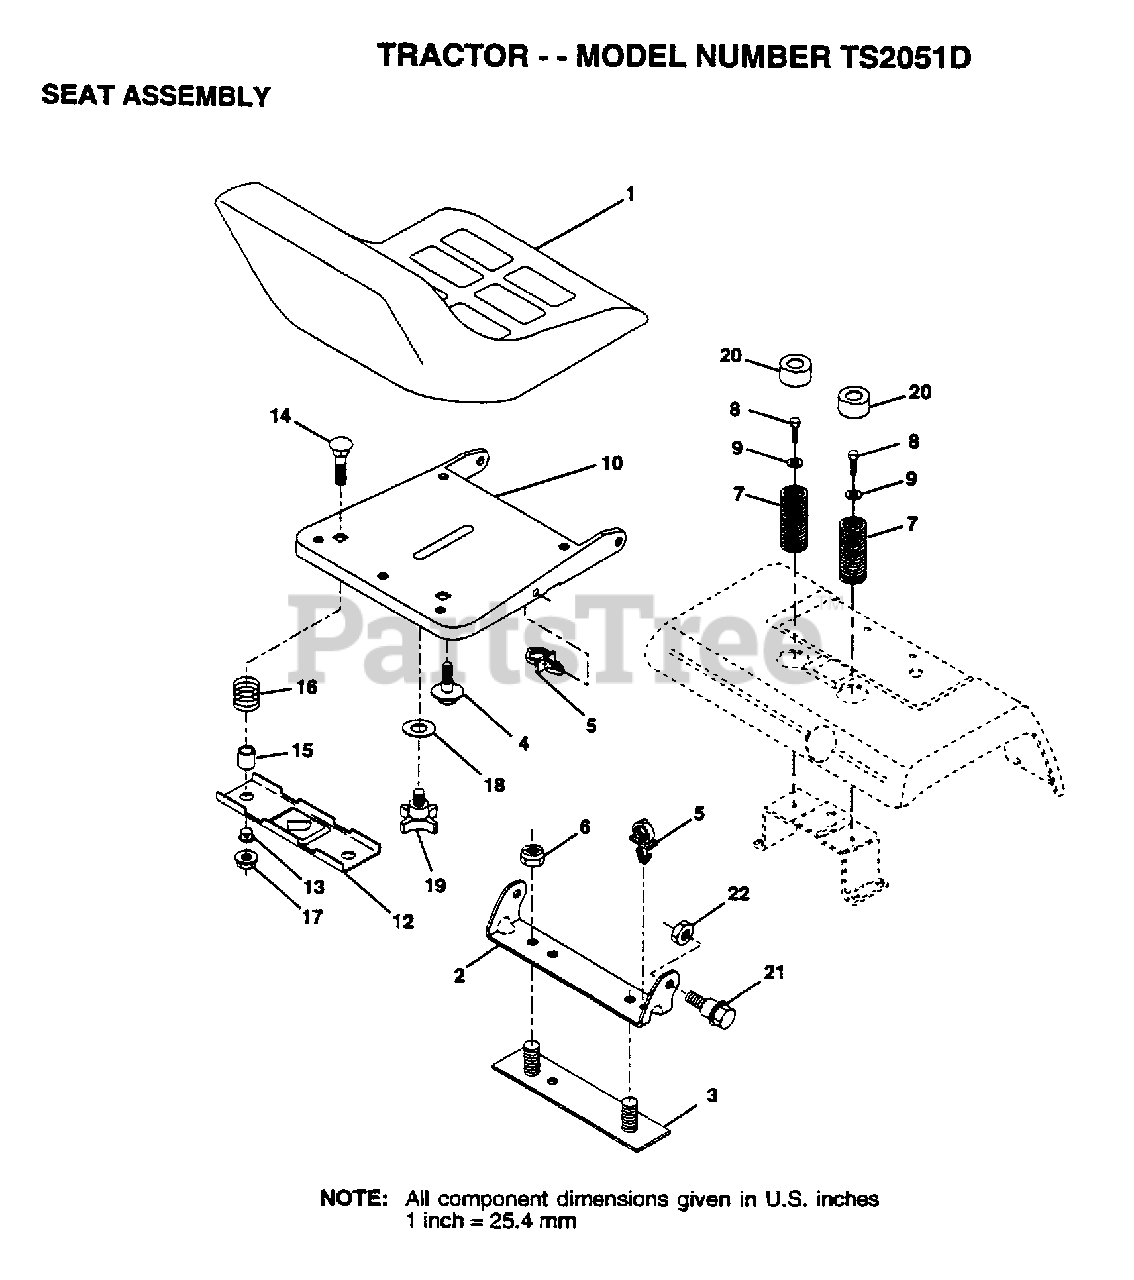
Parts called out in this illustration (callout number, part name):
2	BRACKET PVT SEAT
3	STRAP ASM FENDER
4	"BOLT,SHOULDER"
5	CLIP.PUSH-IN.HING
7	SPRING COMPRESSIO
8	SCREW LT
9	WASHER
12	BRKT SWITCH
13	BUSHING
15	SPACER SPLIT
16	SPRING COMPRESSED
18	WASHER
19	"KNOB 1/2"" YT"
20	CAP SPRING
21	BOLT.SHLD.5/16-18
